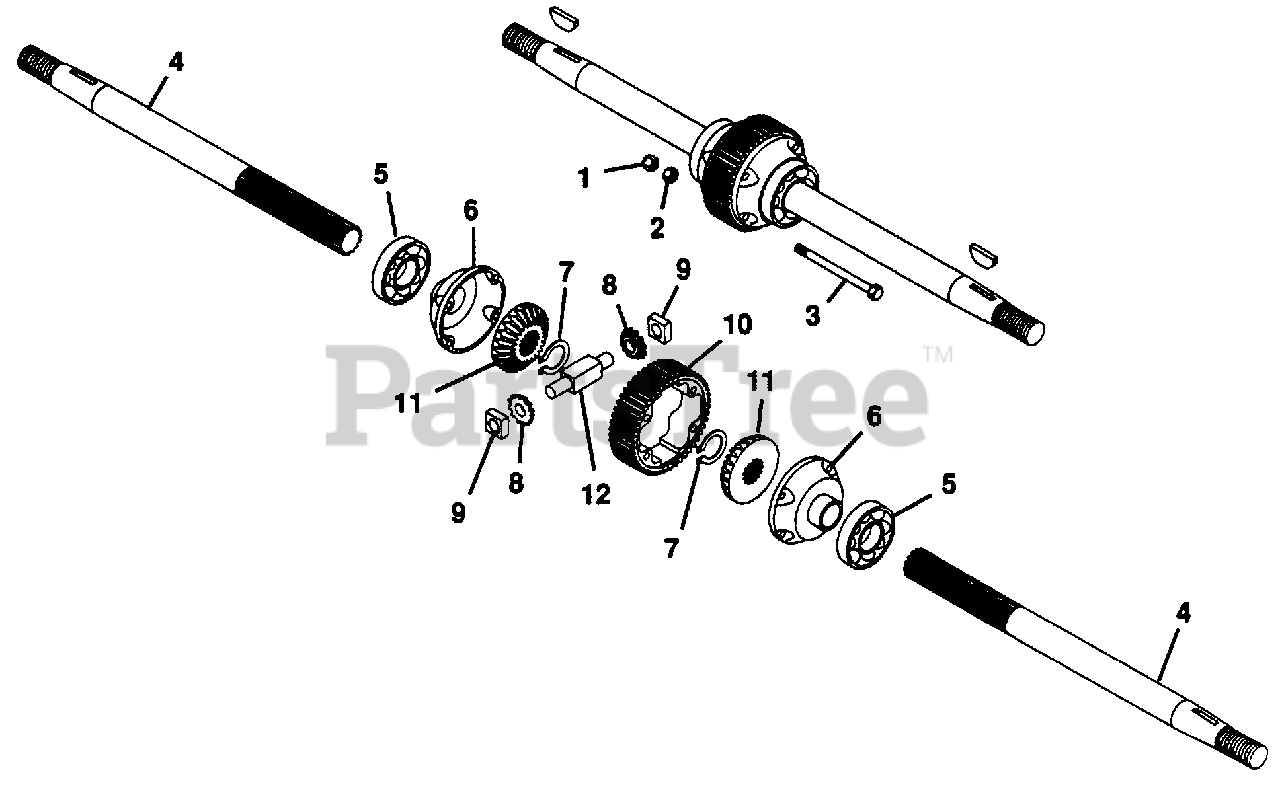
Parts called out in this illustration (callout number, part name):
1	NUT, LOCK 5/16-18
2	NUT, HEX 5/16-18 GRADE-8
3	BOLT, HEX 5/16-18X2.75 GRADE-8
4	AXLE, BEVEL GEAR DIFFERENTIAL
5	BEARING, BALL
6	CAP, DIFFERENTIAL END
7	RING, RETAINING 1.000 SHAFT
8	PINION, BEVEL
9	BLOCK, DRIVE
10	GEAR, FINAL DRIVE
11	GEAR, BEVEL
12	PIN, SPIDER PINION
